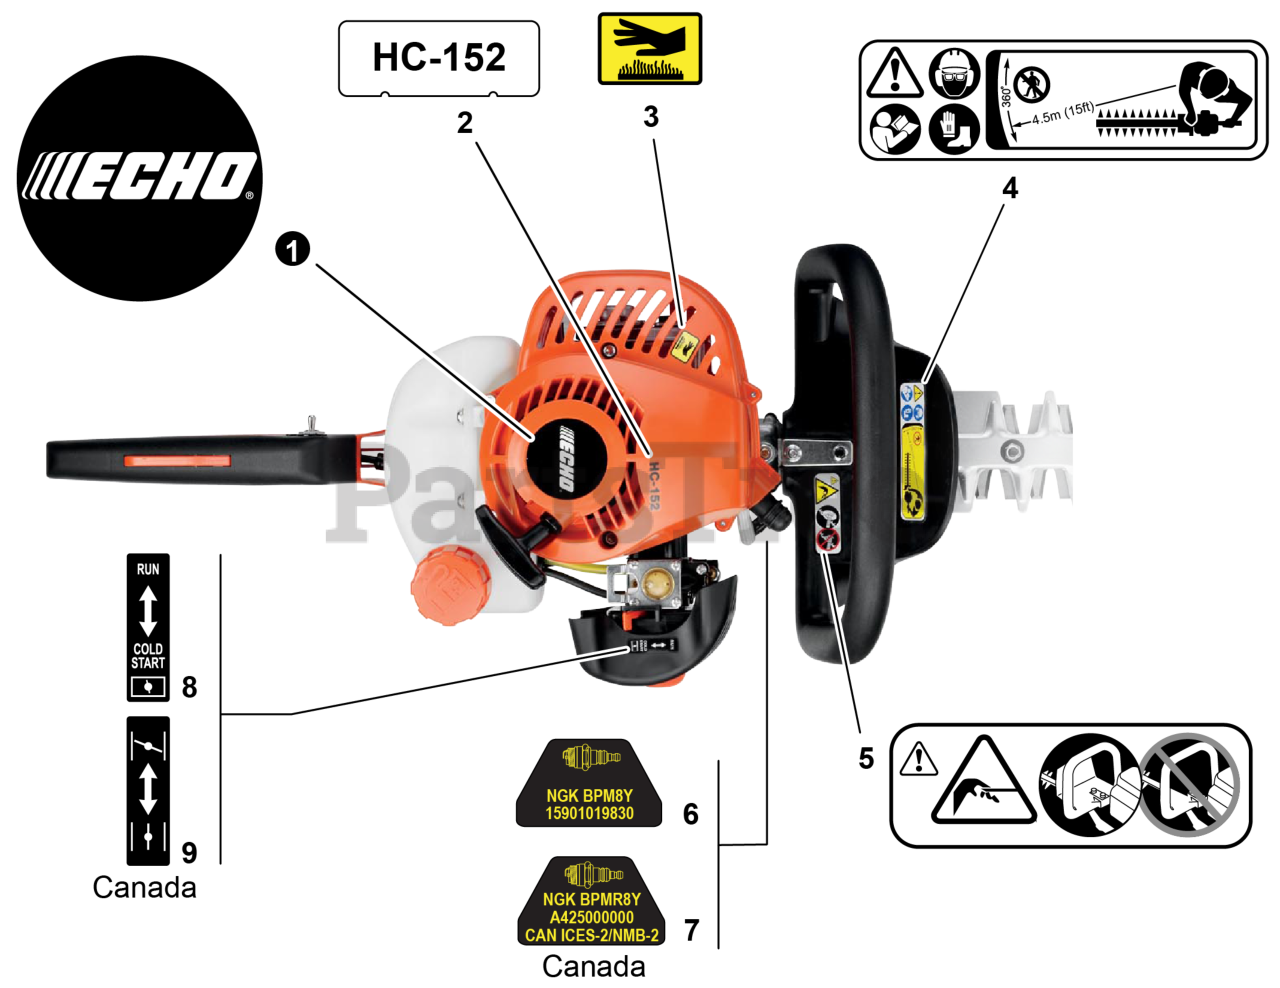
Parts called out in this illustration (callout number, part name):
1	LABEL - STARTER - ECHO
2	LABEL - MODEL HC-152
3	LABEL - CAUTION - HOT
4	LABEL - CAUTION - ISO
5	LABEL - CAUTION
6	LABEL - SPARK PLUG - BPM8Y
7	LABEL - SPARK PLUG - BPMR8Y
8	LABEL - CHOKE
9	LABEL - CHOKE
